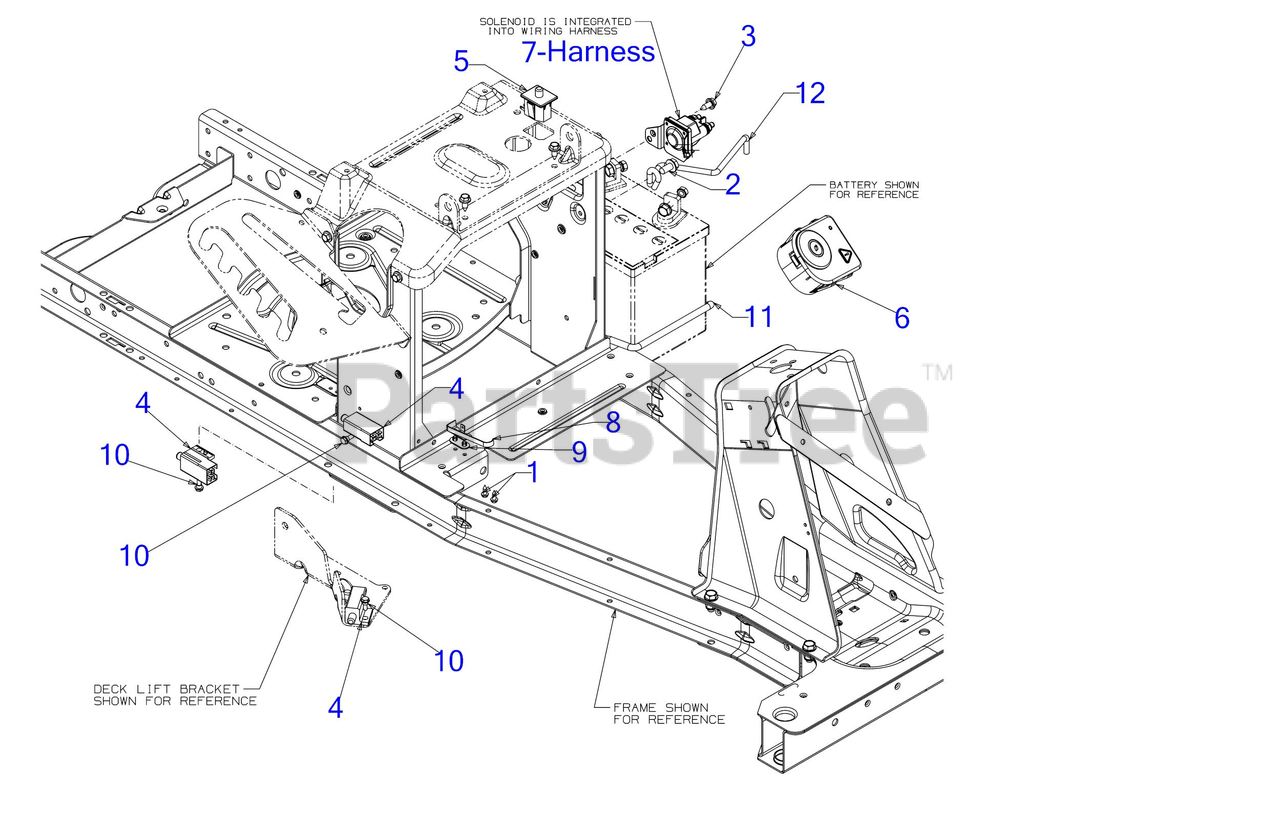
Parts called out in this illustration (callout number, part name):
1	HEX SCREW WASHER HD #8-18 x 0.500
2	SCREW 5/16-18 x .750
3	SCREW 1/4-20X.625
4	INTERLOCK SWITCH (NO/NC)
5	SEAT SWITCH
6	IGNITION MODULE SWITCH RMC (MAN PTO BLK)
7	HARNESS
8	SPRING SWITCH
9	INSULATOR PLATE
10	SHOULDER SCREW
11	BATTERY TRAY ROD
12	BATTERY HOLD DOWN ROD
